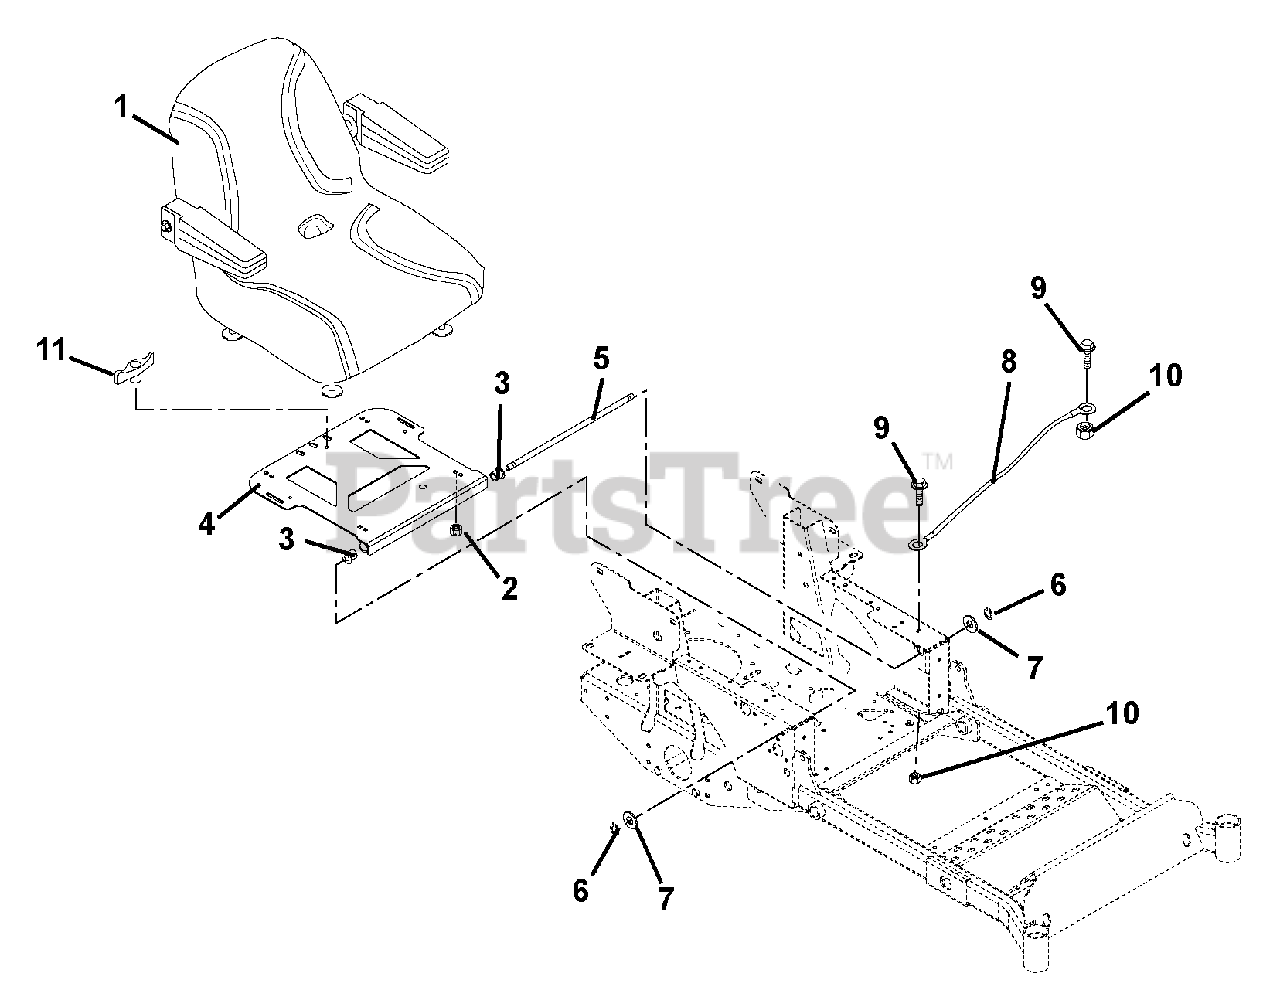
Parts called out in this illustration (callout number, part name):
1	Seat
2	Nut, Nyloc Flange 5/16-18 (056, 065)
2	Nut, Nyloc Flange 5/16-18 (314)
3	Bushing, Flange .515 x .750 x .745 x 1.00
4	Seat Pivot Mount
5	Rod, Seat Frame Pivot
6	Ring, Retaining External .50 x .05
7	Washer, Flat Steel .531 x 1.06 x .095
8	Cable, Hood
9	Bolt, Hex .25-20 x .75 Grade 5
10	Nut, Nyloc Flange .25-20
11	Knob, Wing .312-18
